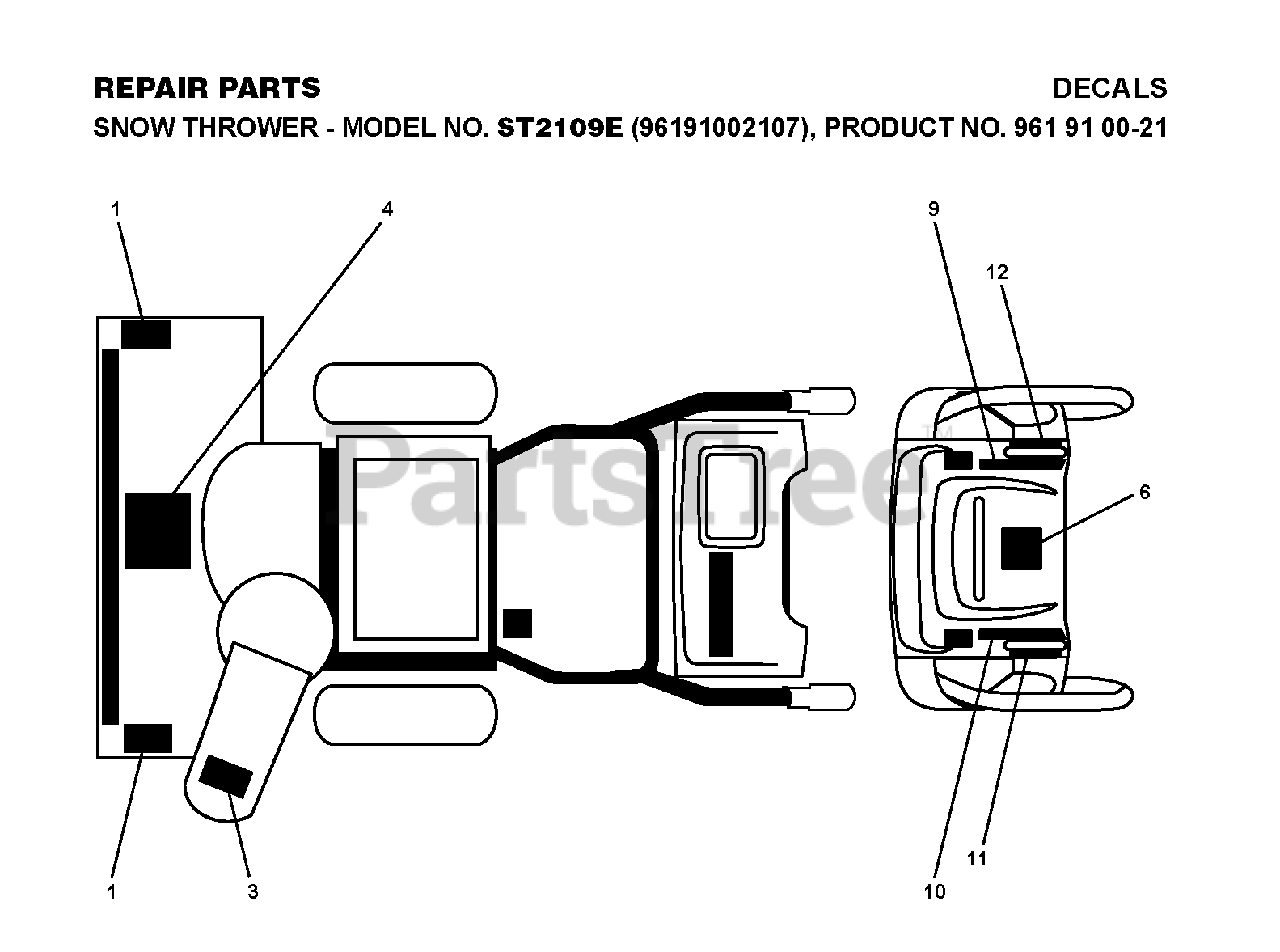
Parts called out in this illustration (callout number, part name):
1	DECAL.AUGER.SAFETY.
3	DECAL.CHUTE.SAFETY.
4	DECAL.AUGER."
6	DECAL.CONSOLE.INSTRUCTION
10	DECAL.REM.DEFLECTOR.LT
11	DECAL.POWER.STEER.LT.TRIG.INT
12	DECAL.POWER.STEER.RT.TRIG.INT
